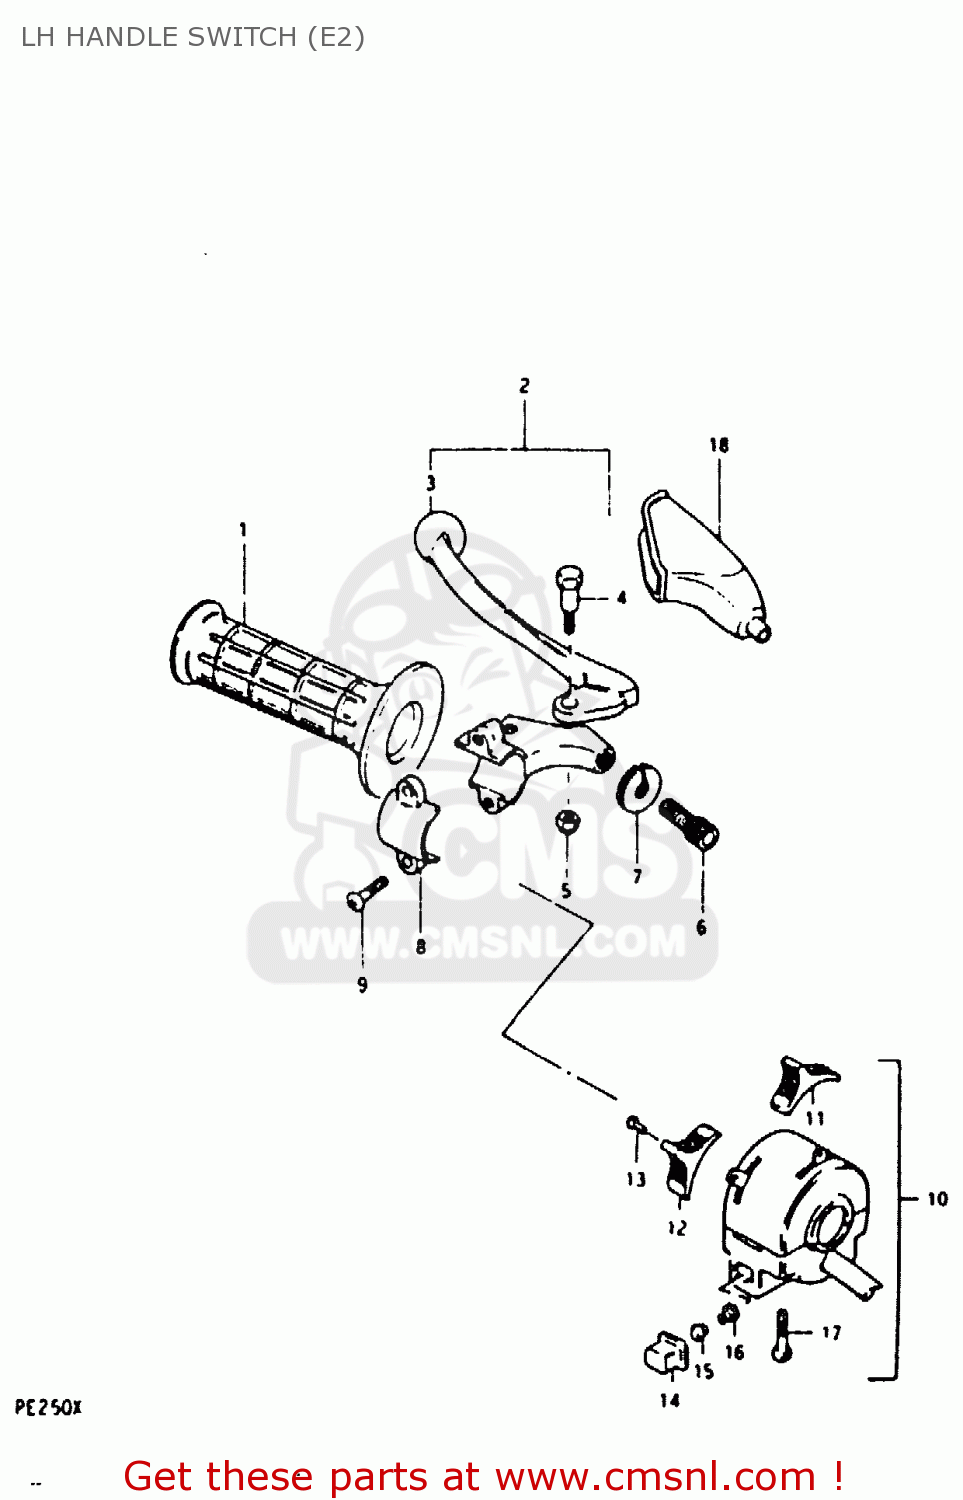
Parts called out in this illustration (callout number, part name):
1	GRIP,LEFT
2	LEVER ASSEMBLY
3	LEVER,CLUTCH
4	BOLT,LEVER
5	NUT 6MM
6	ADJUSTER,CABLE
7	NUT,CABLE ADJUSTER
8	BRACKET,LEVER
9	SCREW
10	SWITCH ASSY, HANDLE LH
11	KNOB,LIGHTING SWITCH
12	KNOB,DIMMER SWITCH
13	SCREW
14	BUTTON,HORN
15	CONTACT
16	SPRING
17	SCREW
18	COVER,CLUTCH LEVER
